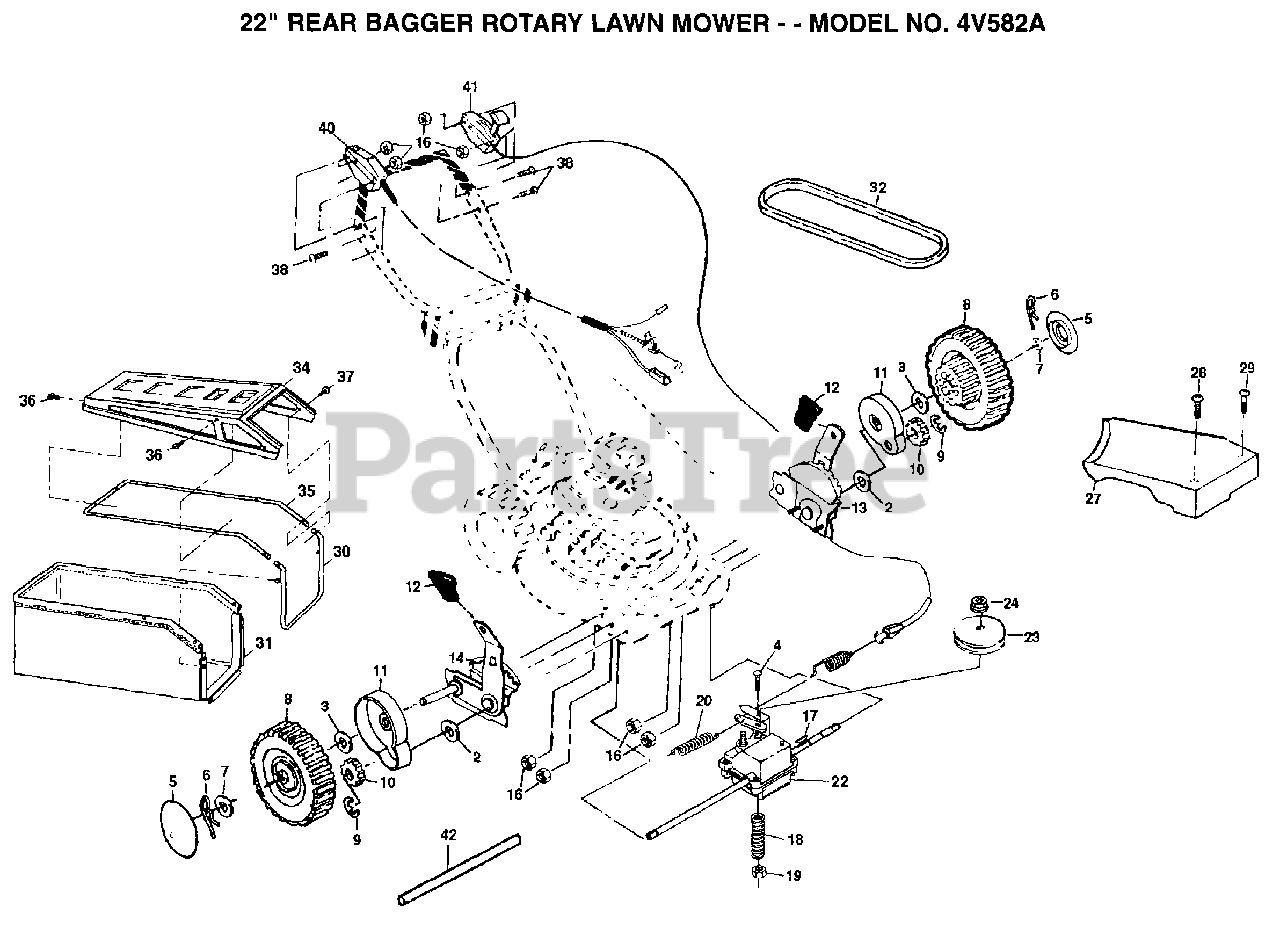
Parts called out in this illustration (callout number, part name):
2	WASHER PM
3	WASHER FLUT
4	BOLT.1/4-20X2.0
5	HUB CAP
6	RETAINER CLIP PM
7	WASHER
8	WHEEL.8X2.LP.PR
10	PINION.GEAR
11	DUST SHROUD PM
12	KNOB PM
17	HI PRO KEY
18	SPRING.TENSION
20	SPRING.RETURN
23	PULLEY.DRIVEN
24	LOCKNUT
27	"COVER.DRIVE 22""RD"
30	"FRAME,CATCHER"
31	GRASS CATCHER
34	"TOP,CATCHER"
35	"TUBE,CATCHER"
37	SCREW
41	CONTROL.DRIVE
42	DRV SHAFT TUBE PM
